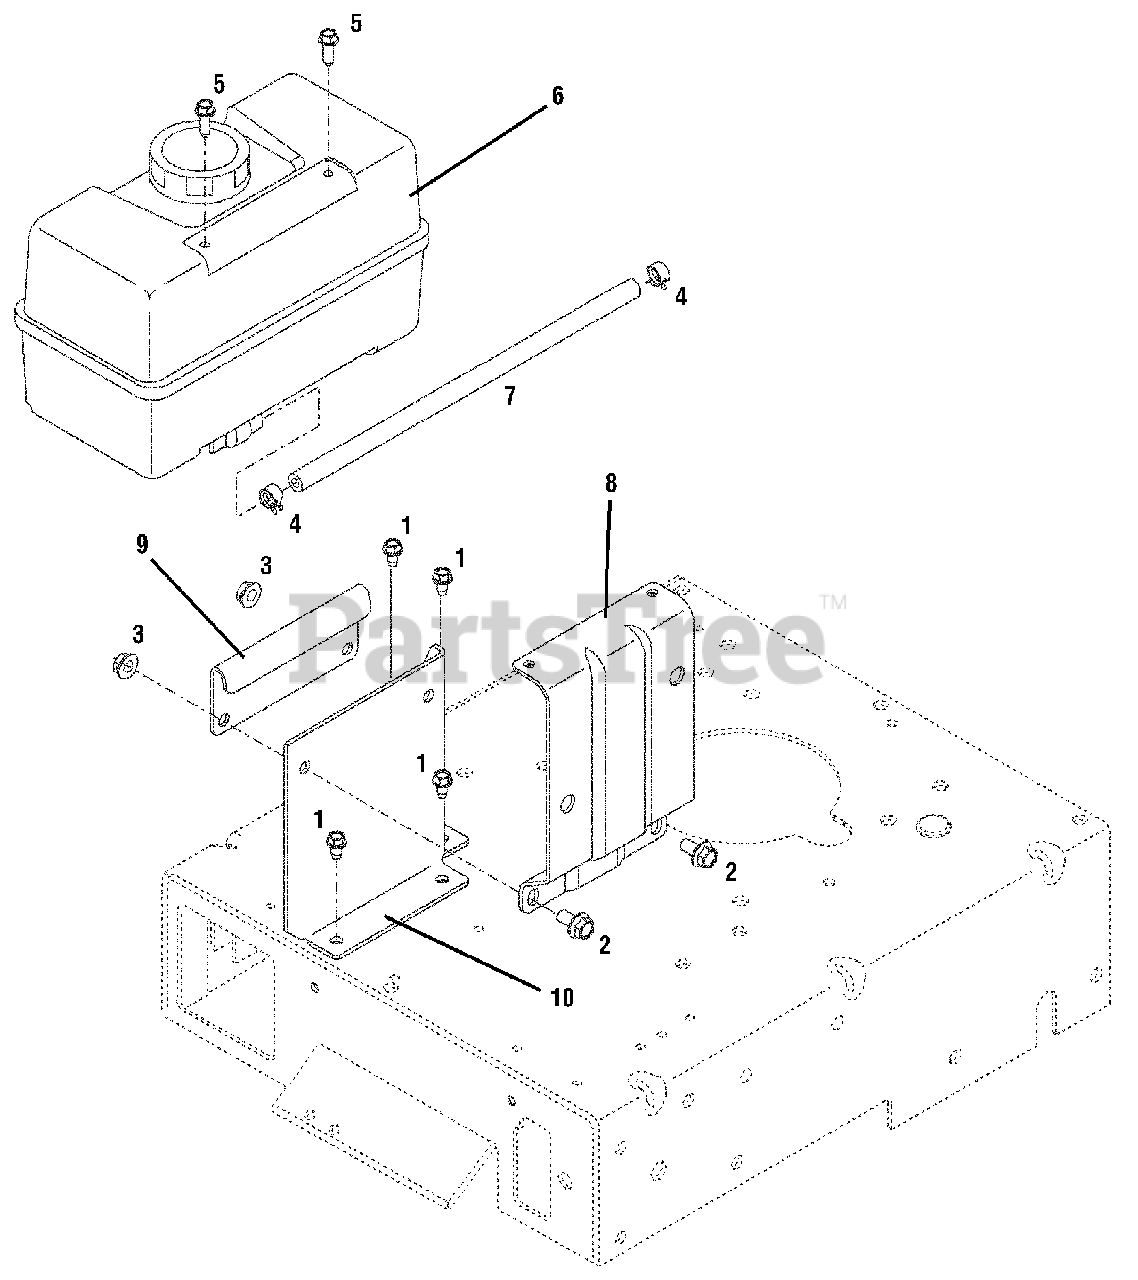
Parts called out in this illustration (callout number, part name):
1	Self-tapping Screw, 1/4-20 x 1/2
2	Hex Flange Screw, 5/16-18 x 5/8
3	Flange Locknut, 5/16-18
4	Hose Clamp
5	Screw, K80 x 3.59
6	Fuel Tank, 1 gal.
7	Fuel Line, 12"
